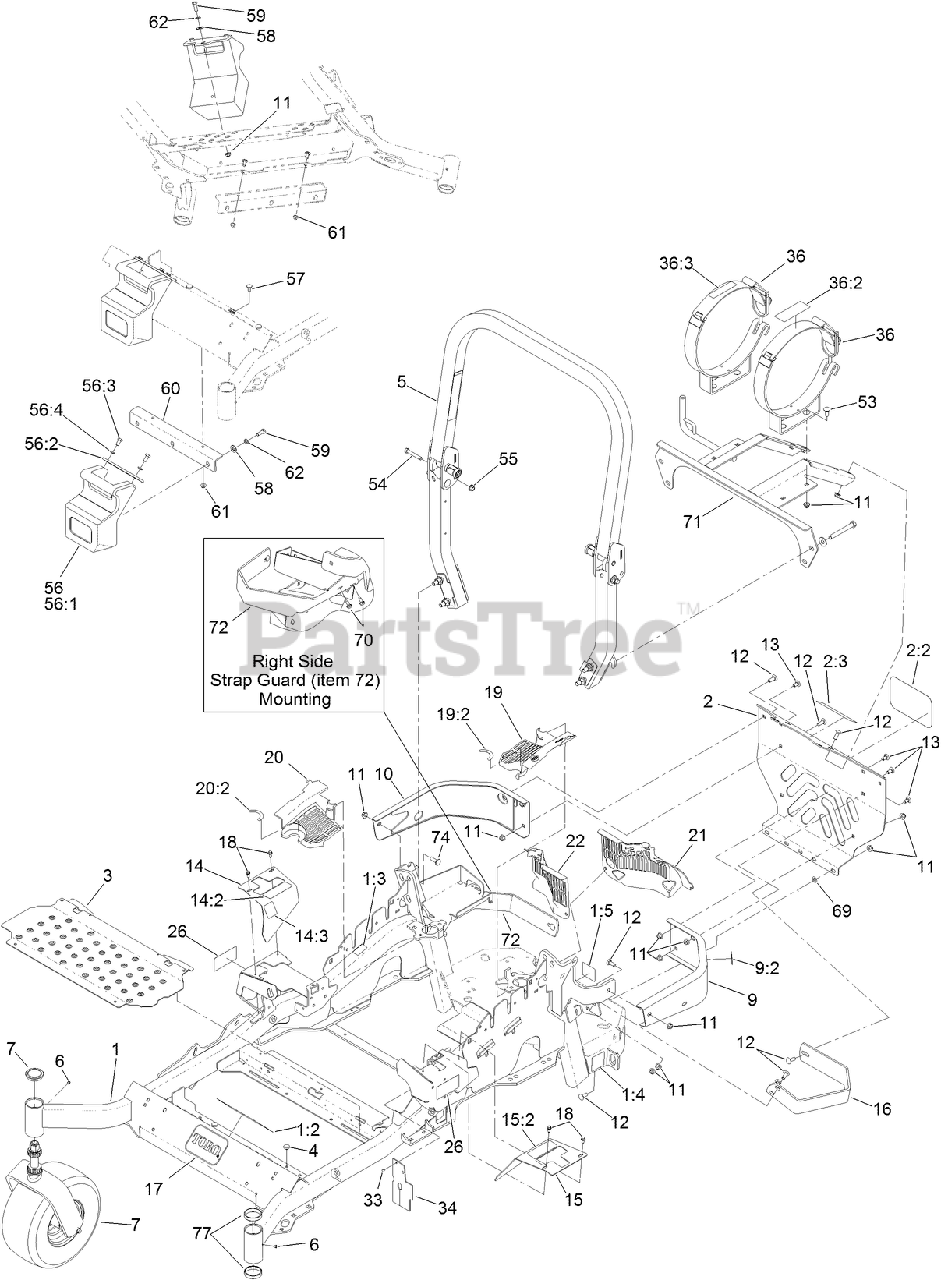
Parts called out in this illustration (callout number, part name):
1	MAINFRAME ASM
1:2	DECAL-WARNING
1:3	DECAL-WARNING, SLOPE
1:4	DECAL-HAZARD, PINCHED FINGER
1:5	DECAL-SPARK ARRESTER
2	LPG REAR GUARD ASM
2:2	DECAL
2:3	DECAL-LPG FUEL TANK REPLACEMENT
3	FLOORPAN
4	BUMPER
5	ROPS ASM
7	Caster Wheel ASM
9	LH BUMPER ASM
9:2	DECAL-WARNING
10	BUMPER-RH
11	NUT-HF, NI
12	SCREW-CARR
13	SCREW-CARR
14	RH MOTION CONTROL COVER ASM
14:2	DECAL-CONTROL, MOTION
14:3	DECAL-PARK BRAKE, CE
15	LH MOTION CONTROL COVER ASM
15:2	DECAL-CONTROL, MOTION
16	GUARD-MUFFLER
17	DECAL
18	SCREW-HWH
19	LH HYDRO GUARD ASM
19:2	DECAL-OIL, HYDRO
20	RH HYDRO GUARD ASM
20:2	DECAL-OIL, HYDRO
21	GUARD-HYDRO, REAR (LH)
22	GUARD-HYDRO, REAR (RH)
33	RIVET-POP
34	DEFLECTOR-AIR FLOW
36	TANK BRACKET ASM (SET)
36:2	DECAL-LPG WARNING
36:3	DECAL-LPG TANK SPEC
53	BOLT-CARR
54	SCREW-HH
55	NUT-LOCK
56	WEIGHT ASM
56:1	WEIGHT-43 LB
56:2	TAB-SUPPORT, WEIGHT
56:3	SCREW-HH
56:4	WASHER-LOCK
57	SCREW-CARR
58	WASHER-FLAT
59	SCREW-HH
60	BRACKET-MOUNT, WEIGHT
61	NUT-HF, NI
62	WASHER-LOCK
69	NUT-PUSH
70	SCREW-HWHTF
71	SUPPORT-LPG TANK
72	STRAP-GUARD
74	BOLT-CARR
77	CUP-BEARING
